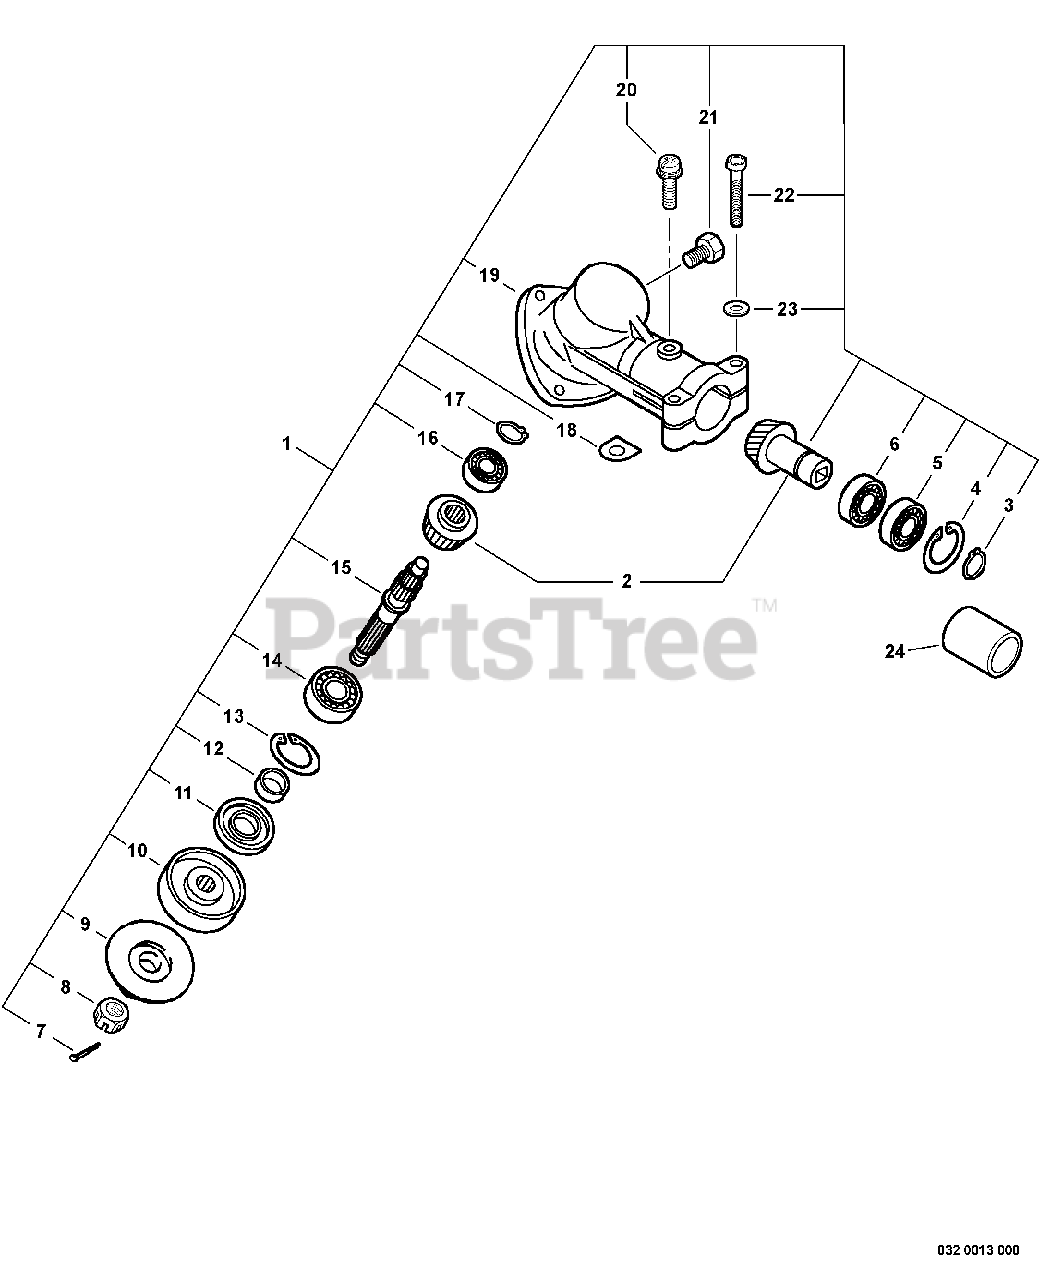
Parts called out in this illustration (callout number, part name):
1	GEAR CASE ASSY
2	GEAR SET
3	RING, SNAP Ø10
4	RING, SNAP Ø22
5	BEARING, BALL 6900Z
6	BEARING, BALL 6900
7	PIN, COTTER 2×22
8	NUT 10×1.25 LH
9	PLATE, ADAPTOR - LOWER
10	PLATE, ADAPTOR - UPPER
11	SEAL, OIL 22
12	SPACER 11.8×15×9
13	RING, SNAP Ø32
14	BEARING, BALL - 6201 C3
15	SHAFT, GEAR
16	BEARING, BALL 609
17	RING, SNAP Ø12
19	HOUSING, GEAR CASE
20	SCREW 5×12
21	BOLT 8×8 SP
22	BOLT 5×30
23	WASHER, FLAT 5.5×10×0.8
